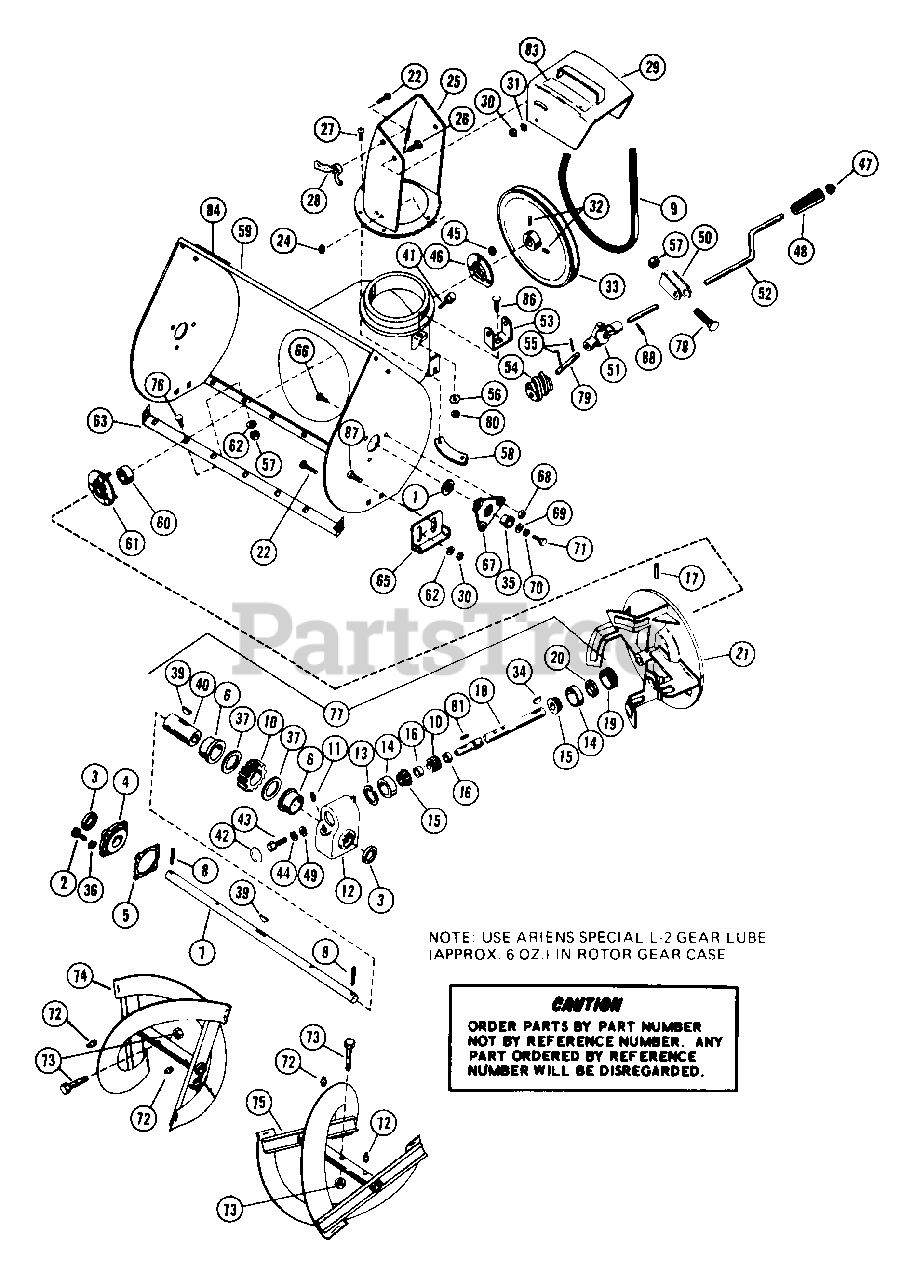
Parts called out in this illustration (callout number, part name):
1	WSHR-FL-STL 1.010X1.505X.062PL
2	BLT-HEX .25-20X.75 PL GR2
3	SEAL 1.625X2.125X.250
4	GEAR CASE COVER
6	BSHG-FLG .683X1.87X1.68X2.250
7	SHAFT, 32" RAKE - 1.00 DIA.
8	PIN-ROLL .188X1.50
10	WORM & GEAR SERVICE ASSEMBLY
11	PIPE PLUG
12	GEAR CASE - CAST IRON
13	RG-RTNG INT 1.781 HSG X.062
14	BRG-CUP 1.781X.475
15	BRG-CONE .750X.61
16	BSHG, SPCR .755X1.12X.50 PM
17	PIN-ROLL .313X1.75
18	SHAFT, WORM - 1.00 DIA.
19	ADJUSTMENT PLUG - 1" SHAFT
20	SEAL 1.000X1.312X.150
21	FAN, 12"
22	BLT-RDHDSQNK .38-16X.75 SHT PL
25	DISCHARGE CHUTE
26	BLT-HEX .38-16X.75 PL GR2
27	SCR-TAP 10-24X.375 CRPH 1A
28	WING NUT
29	SERVICE DEFLECTOR ASSM
30	NUT-LK-CTR .375-16 GR A PL
31	WSHR-LK .375X.115 HVY PL
32	SCR-SET .32-18X.38 SKHCUPNL OH
33	PLY-? 9.0X.75
34	KEY-WDRF .188X.875X.375 SAE11
35	BSHG-FLG 1.000X1.12X.62X1.50BR
36	WSHR-LK-EXT. 250 ID
37	WSHR-FL-STL 1.625X2.500X.012
39	KEY-WDRF .25X.875X.375 SAE A
40	GEAR CASE SHAFT
41	BLT-SCRHFWH .38-16X.75 PL
42	DUST CAP
43	BLT-HEX .31-18X.75 PL GR2
44	WSHR-LK .312X.097 PL HVY
45	NUT-LK-CTR .250-20 PL
47	CAP, 3/8 ROD YWZC
49	WSHR-FL-STL .328X1.0X.094
50	BRACKET
51	UNIVERSAL JOINT ASSEMBLY
52	CHUTE CONTROL CRANK
53	WORM CLEVIS
54	WORM GEAR
55	PIN-ROLL .125X.75
56	WSHR-LK .313X.062
57	NUT-LK .312-18 GR A PL
58	CHUTE CLAMP
59	BLOWER HOUSING 32IN
60	BRG-BALL .750X1.750X.50
61	BEARING FLANGE
62	WSHR-FL-STL .38X.875X.083 PL
63	SCRAPER BLADE
65	RUNNER
66	SCR-SLTR-SERNK .25-20X.62 PL
67	BEARING SUPPORT
68	NUT-LK-FLG .250-20 PL
69	WSHR-FL-STL .511X1.441X.125 PL
70	WSHR-LK .500X.151 HVY PL
71	BLT-HEX .50-13X1.00 PL GR2
72	SPIN DRIVE ZERK FITTING
73	SHEAR BOLT SERVICE ASSEMBLY
74	RAKE, RIGHT-32"(1ID X 15.75OD)
75	RAKE, LEFT-32"(1"ID X 15.75OD)
76	BLT-RDHDSQNK .312-18X.62 PL
77	GEAR CASE - CAST IRON
78	BLT-RDHDSQNK .31-18X1.75 SHTPL
79	WORM SHAFT
80	NUT-HEX .312-18
81	KEY-SQ .188X1.0X.188 SAE 8630
83	CAUTION LABEL
84	ARIENS SCRIPT NAME PLATE
86	BLT-RDHDSQNK .31-18X.75 GR5 PL
87	BLT-RDHDSQSHNK .38-16X1.00 PL
88	PIN-HAIR INT .09X.62X2.25
